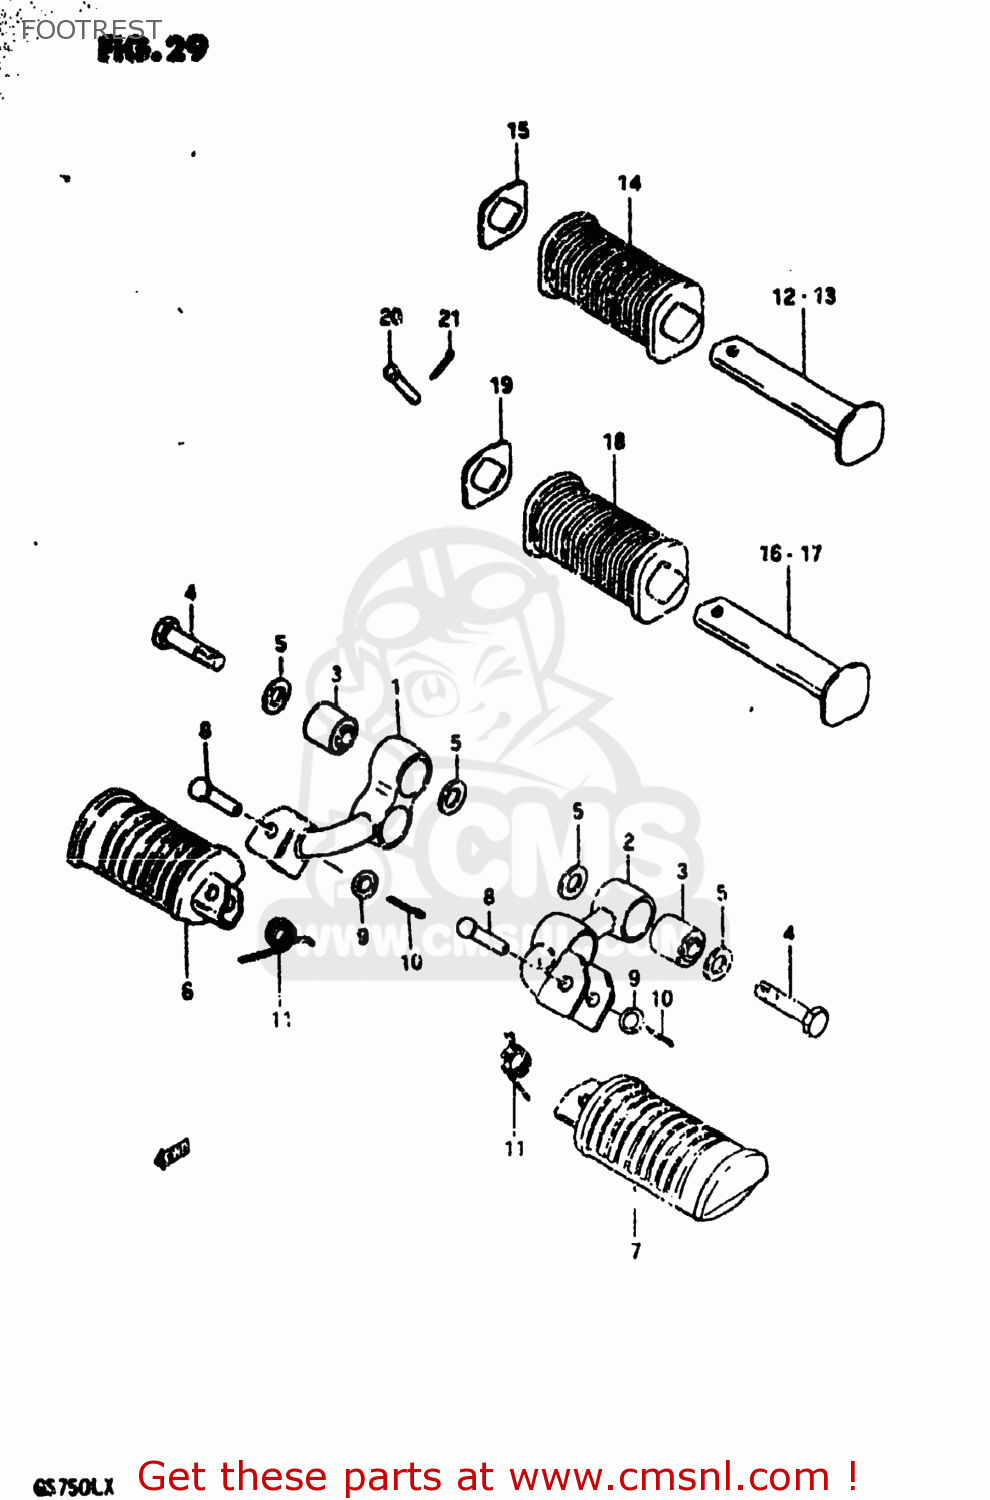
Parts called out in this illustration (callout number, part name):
1	BAR,FRONT FOOTREST,RIGHT
2	BAR,FRONT FOOTREST,LEFT
3	BUSH
4	BOLT
5	WASHER
6	RUBBER,FRONT FOOTREST
7	FOOTREST
8	PIN
9	WASHER
10	PIN
11	SPRING
12	BAR,REAR FOOTREST
13	BAR,REAR FOOTREST
14	RUBBER,REAR FOOTREST
15	WASHER,REAR FOOTREST RUBBER
16	BAR,REAR FOOTREST,RIGHT
17	BAR,REAR FOOTREST,LEFT
18	RUBBER,PILLION FOOTREST
19	WASHER,PILLION FOOTREST RUBBER
20	PIN
21	PIN
